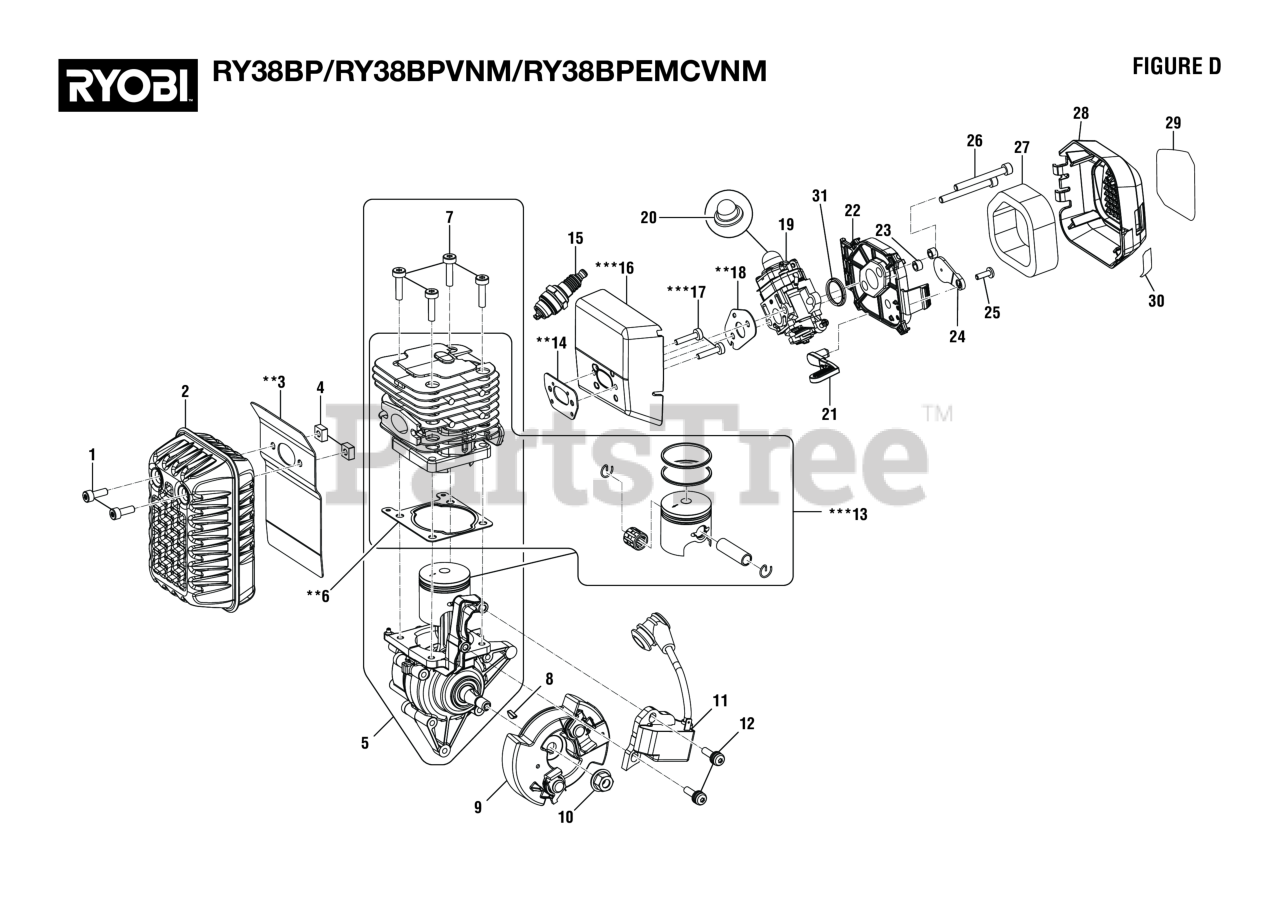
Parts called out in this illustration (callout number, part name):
1	Bolt (M5 x 14 mm)
2	Muffler Assembly
3	Exhaust Gasket
4	Square Nut (M5)
5	Short Block Assembly
6	Cylinder Gasket
7	Cap Screw (M5 x 20 mm, T25 Torx Soc. Hd.)
8	WOODRUFF KEY (10 mm X 3 mm)
9	Flywheel Assembly
10	Flange Nut (M8, Flywheel)
11	Ignition Module
12	Cap Screw w/Washer (M5 x 16 mm, T25 Torx Soc. Hd.)
13	Top End Engine Kit
14	Gasket (Heat Dam to Cylinder)
15	Spark Plug (Champion RCJ6Y)
16	Heat Dam
17	Screw (M5 x 25 mm, T25 Torx Pan Hd.)
18	Gasket Carb-Heat Dam
19	Carburetor Assembly
20	Purge Bulb
21	Choke Lever
22	Air Box Base
23	Washer (ID5.8 x OD11.5 x 1.7t)
24	Choke Plate
25	Screw (M4 x 12 mm, Slotted Recessed Pan Hd.)
26	Cap Screw (M5 x 45 mm, T25 Torx Soc. Hd.)
27	Air Filter (Element)
28	Air Box Cover w/Labels
29	Starting Instructions Label
30	Choke Label
